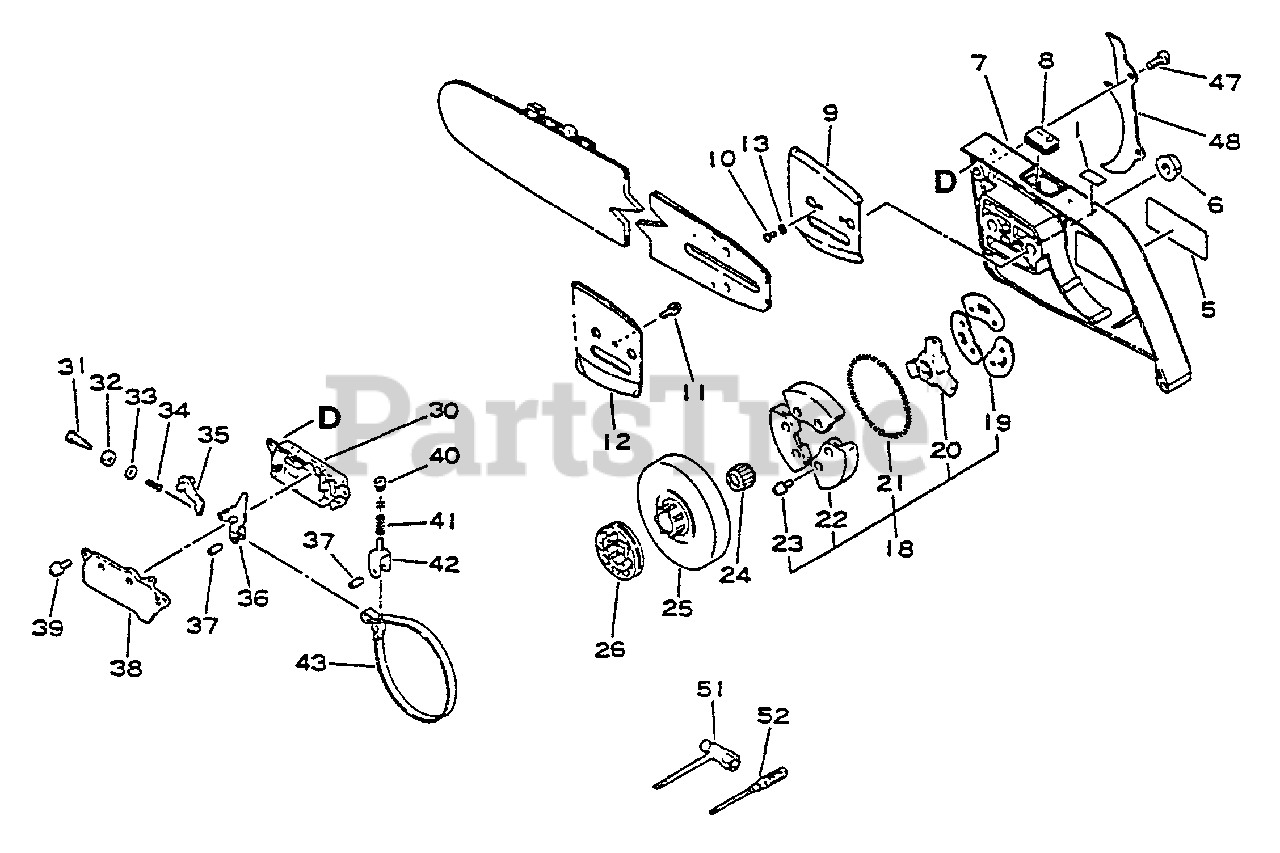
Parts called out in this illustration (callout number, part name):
1	LABEL, CAUTION
5	LABEL - ECHO
6	NUT, FLANGE M8×1.25
7	GUARD, SPROCKET
9	PLATE, GUIDE - OUTER
10	SCREW 3×6
11	SCREW - 4×8
12	PLATE, GUIDE - INNER
13	LOCKWASHER - 3
18	CLUTCH ASSY
19	PLATE, CLUTCH
20	HUB, CLUTCH
21	SPRING, CLUTCH
22	SHOE SET, CLUTCH (3PCS)
23	SCREW - 4×8
24	BEARING, NEEDLE
25	DRUM, CLUTCH
26	SPROCKET, 0.325 RIM
30	COVER, BRAKE
34	SPRING ,BRAKE
35	STOPPER, BRAKE
36	LEVER, BRAKE
37	PIN, SPRING 4×10
39	SCREW - 4×10
42	ADJUSTER, BRAKE BAND
43	BAND, BRAKE
48	SPIKED BUMPER KIT
51	T-WRENCH 13×19×180
52	SCREWDRIVER, PHILLIPS
